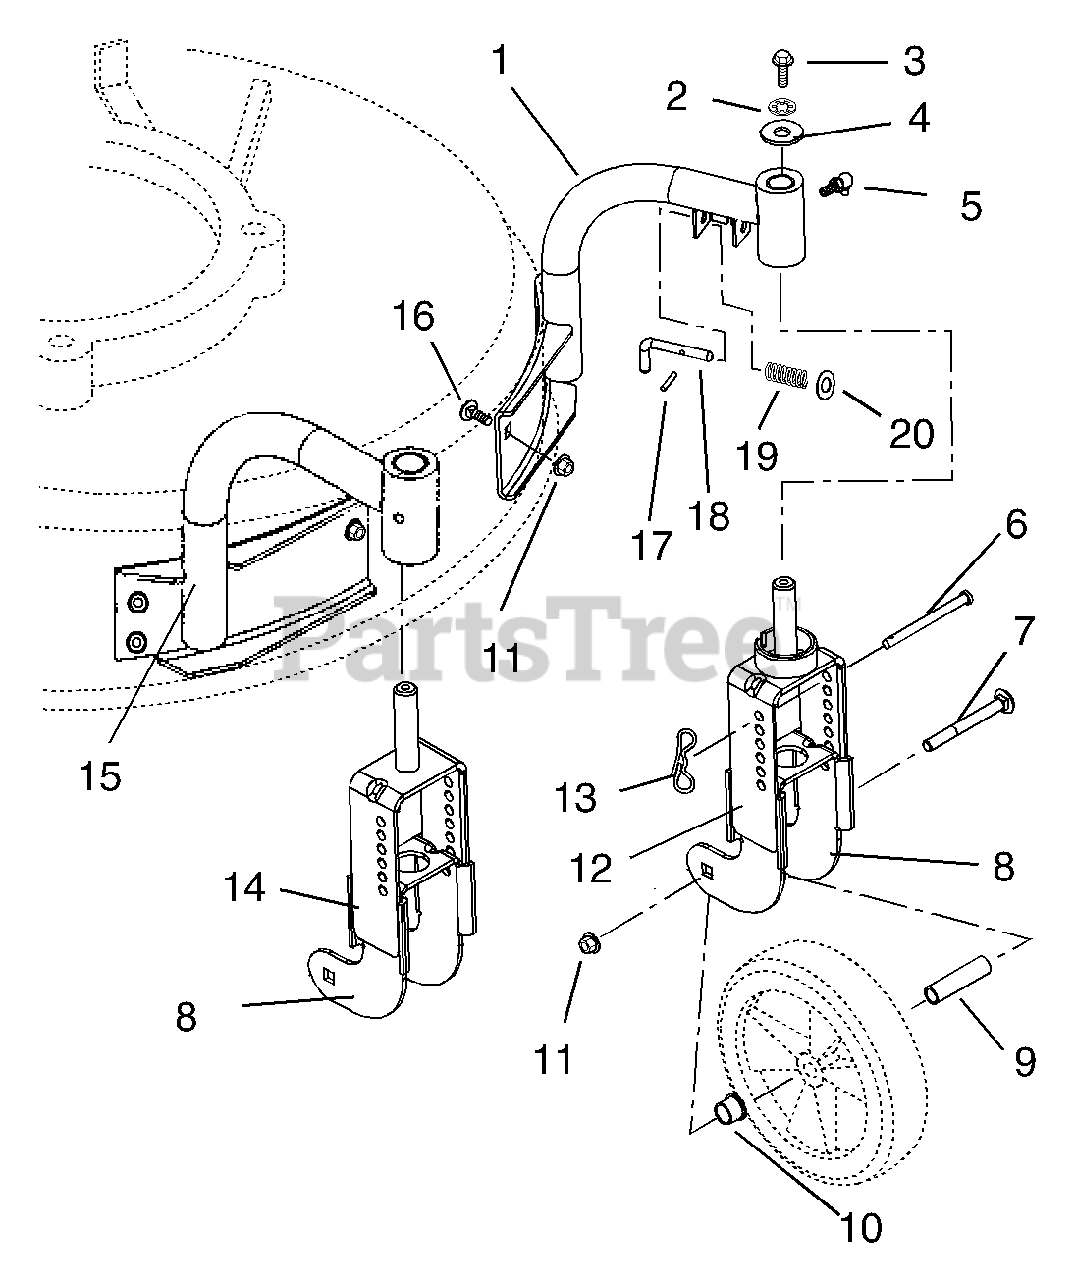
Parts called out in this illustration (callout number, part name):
1	ASSY. LH MOUNT W/BUSHINGS
2	@WSHR-LK .25X.062 REG YWZC
3	@BLT-HEX .25-20X.75 GR5 YWZC
4	WSHR-FL-STL .281X1.000X.063
5	FTG-LUBE .25-28X.256 YWZC
6	PIN, HEIGHT ADJUSTMENT
7	BLT-RDHDSQSHNK.31-18X2.75G2YWZ
8	YOKE-INNER
9	SPCR, WHEEL .385X.500X2.00
10	BSHG-FLG .500X.625X.500X.750
11	@NUT-SPNLK-FLG .312-18 YWZC
12	WELDMENT, LH OUTER YOKE
13	PIN, BOW TIE LOCKING COTTER
14	WELDMENT, RH OUTER YOKE
15	ASSY, RH MOUNT W/ BUSHINGS
16	@BLT-RDHDSQNK .31-18X.50 G5YZ
17	PIN-ROLL .093X1.00
18	PIN, LOCKOUT
19	SPRG, COMP--SWVL LOCKOUT
20	@WSHR-FL-STL.281X.62X.065 YWZC
